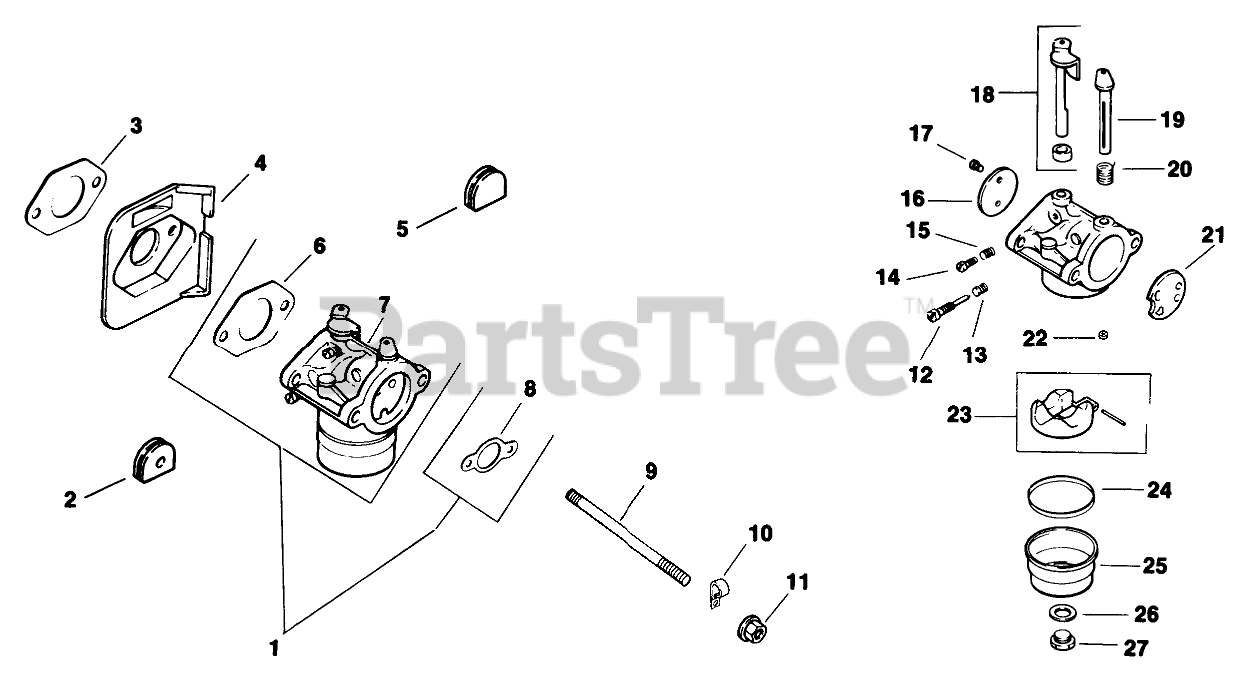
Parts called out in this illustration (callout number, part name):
1	Kit-Carburetor
2	Grommet
3	Gasket
4	Deflector
5	Grommet
6	Gasket
7	Carburetor (Ref.)
8	Gasket
10	Clamp
12	Needle-Idle
13	Spring-Idle
14	Screw-Idle
15	Spring-Idle
16	Plate-Throttle
17	Screw-Throttle Plate
18	Shaft-Throttle
19	Shaft-Choke
20	Spring
21	Plate-Choke
22	Jet-Main
23	Kit-Float
24	Gasket-Bowl
25	Bowl
26	Gasket
27	Screw-Bowl
